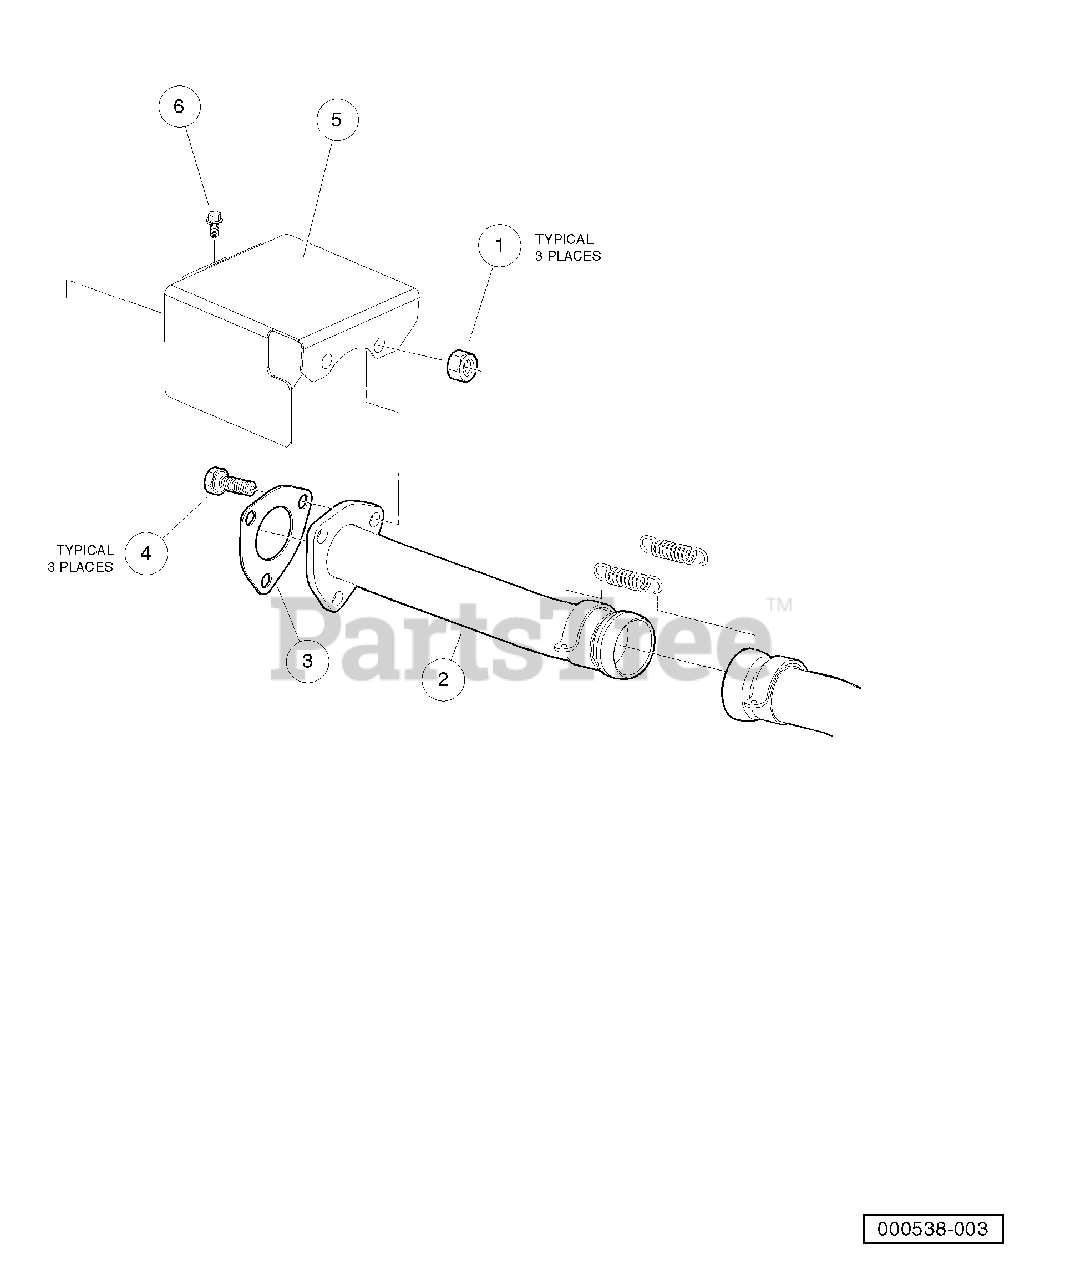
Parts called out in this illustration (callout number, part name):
1	Nut,m8,all Metal Lock
2	Pipe, Exhaust Diesel Main
3	Gasket, Exhaust Diesel
4	Bolt, M8 X 1.25 X 40 with Loctite
5	Shield, Diesel Exhaust
6	Bolt, D722, Exhst Manfld Cover
